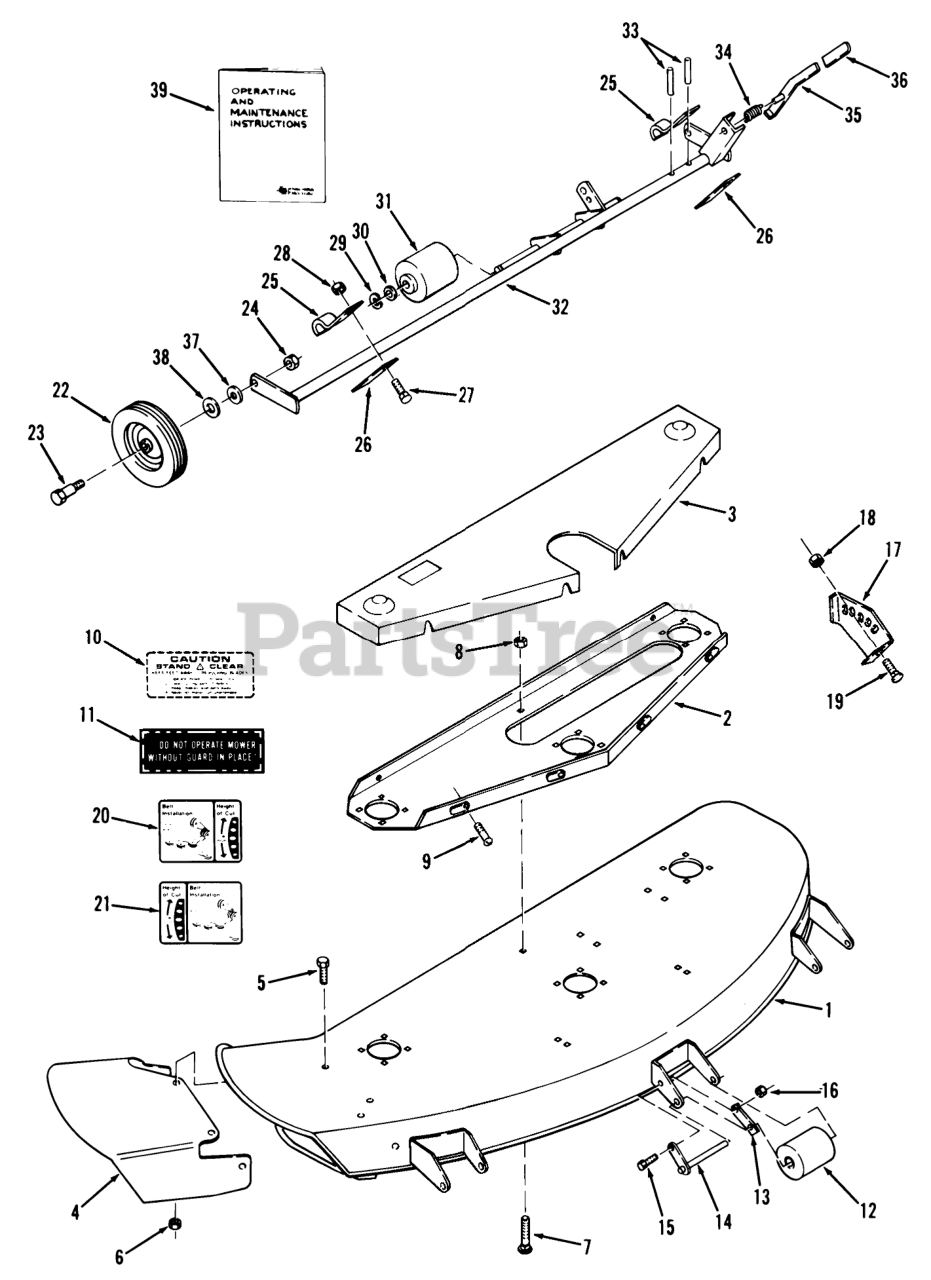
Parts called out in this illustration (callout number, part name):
1	Deck-42"
2	Support
3	COVER R
4	Chute Extension
5	Bolt
6	Nut
7	Bolt-Carriage
8	NUT
9	Bolt
10	Caution Decal
11	Decal-Caution
12	Roller
13	SPRING ROLLER STOP
14	Roller Shaft
15	H H C S
16	Nut
17	Quadrant
18	NUT
19	Bolt
20	DECAL-HEIGHT & BELT
21	DECAL-HEIGHT & BELT
22	Wheel 6 x 1.75
23	BOLT-SHOULDER
24	Nut
25	Machine Bolt
26	Bar
27	Bolt
28	NUT
29	E Ring
30	Washer
31	Roller
32	Support Ass-y. Gage Wheel
33	PIN-SPIROL
34	SPRING-COMPRESSION
35	LEVER ASSY R
37	WASHER
38	WASHER
39	Operating and Maintenance Instructions
